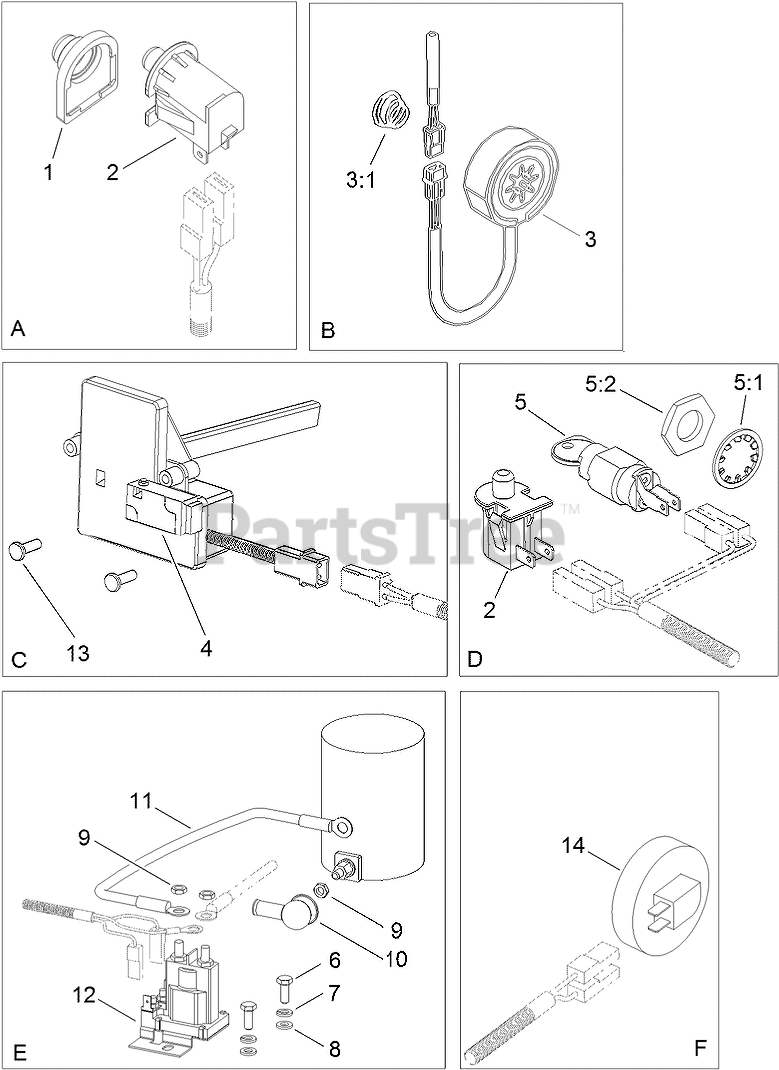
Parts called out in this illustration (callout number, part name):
1	COVER-PROTECTIVE
2	SWITCH-DELTA
3	MAGNET ASM
3:1	SPRING-COMPRESSION
4	SWITCH-OMRON
5	STARTER SWITCH ASM
5:1	WASHER-TOOTH, INTERNAL
5:2	NUT-HH
6	SCREW-HH
7	WASHER-SPRING
8	WASHER-FLAT
9	NUT-HHF
10	BOOT-RUBBER
11	LEAD-STARTER, ELECTRIC
12	Solenoid
13	Screw
14	SWITCH-SEAT
